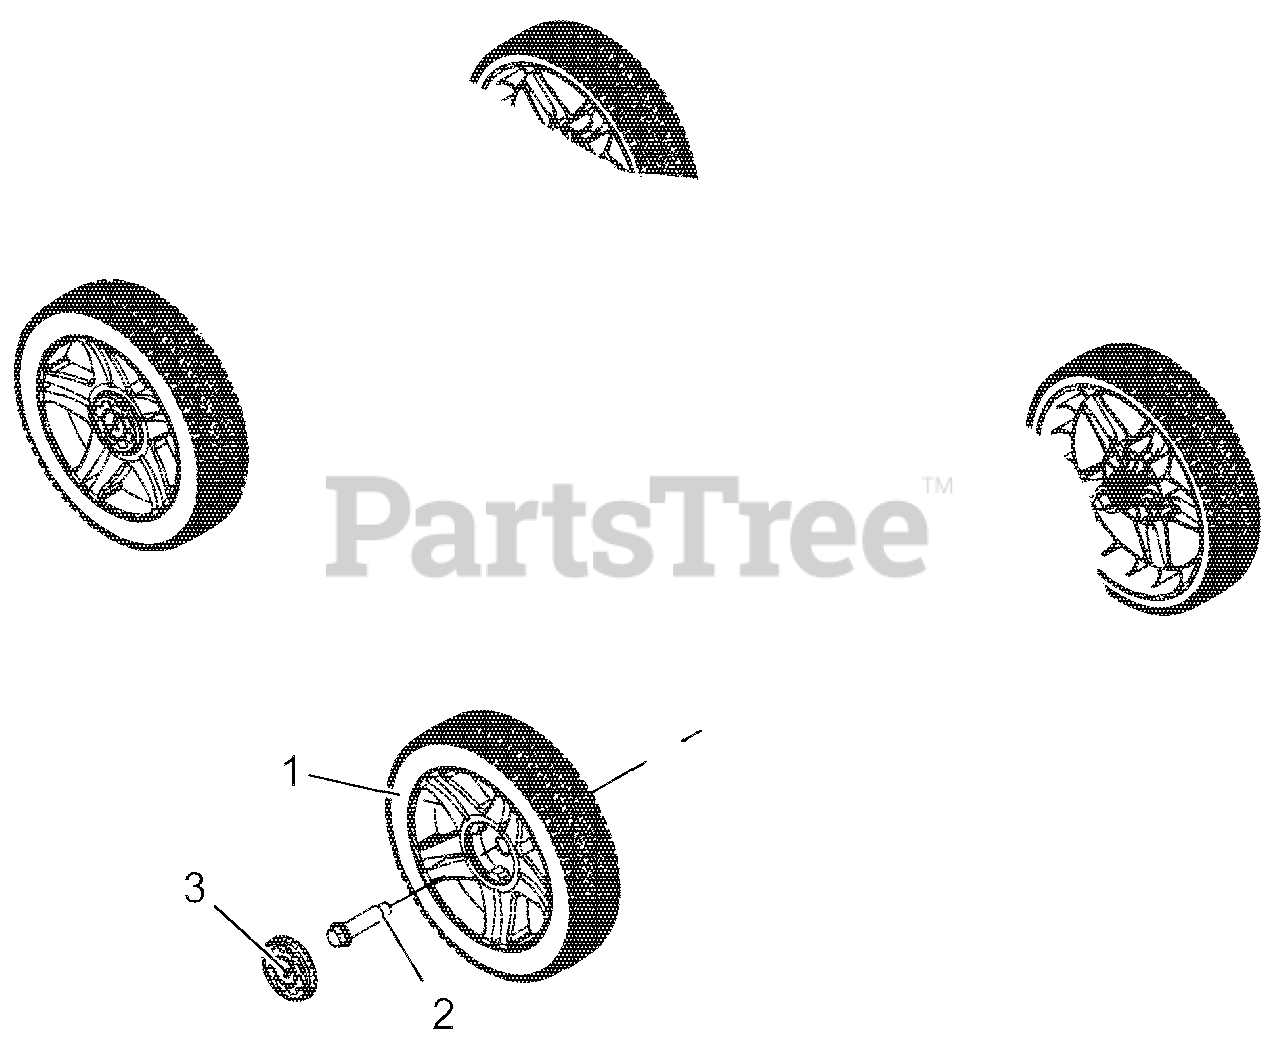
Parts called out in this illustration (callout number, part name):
1	ASSEMBLY, RAZOR WHEEL/BSHG
2	BOLT, WHEEL SHOULDER
3	CAP, LM WHEEL HUB
